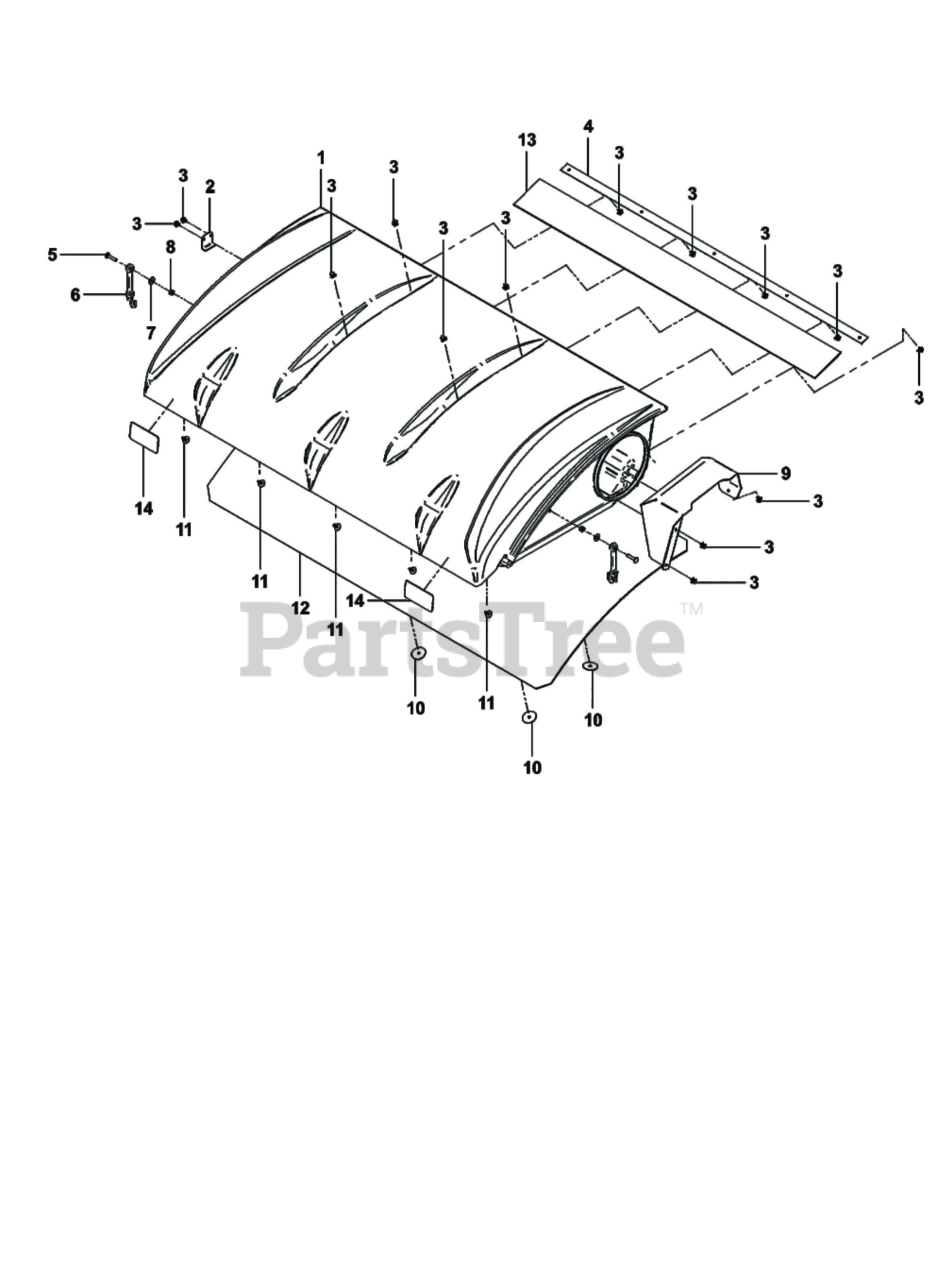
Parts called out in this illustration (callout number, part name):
1	PRO 3 BAGGER TOP
2	HINGE STOP PLATE
3	RIVET-PLASTIC 5MM
4	DUST GUARD BRACE
5	BOLT-1/4-20 x 1-1/
6	RUBBER STRAP W/HOOKS
7	FLAT WASHER
8	NUT-NYLOCK 1/4-20
9	GRASS DEFLECTOR
10	WASHER-FENDER 3/16
11	FLAT HEAD FASTENER
13	DUST GUARD
14	LABEL-2 x 4 RED RE
